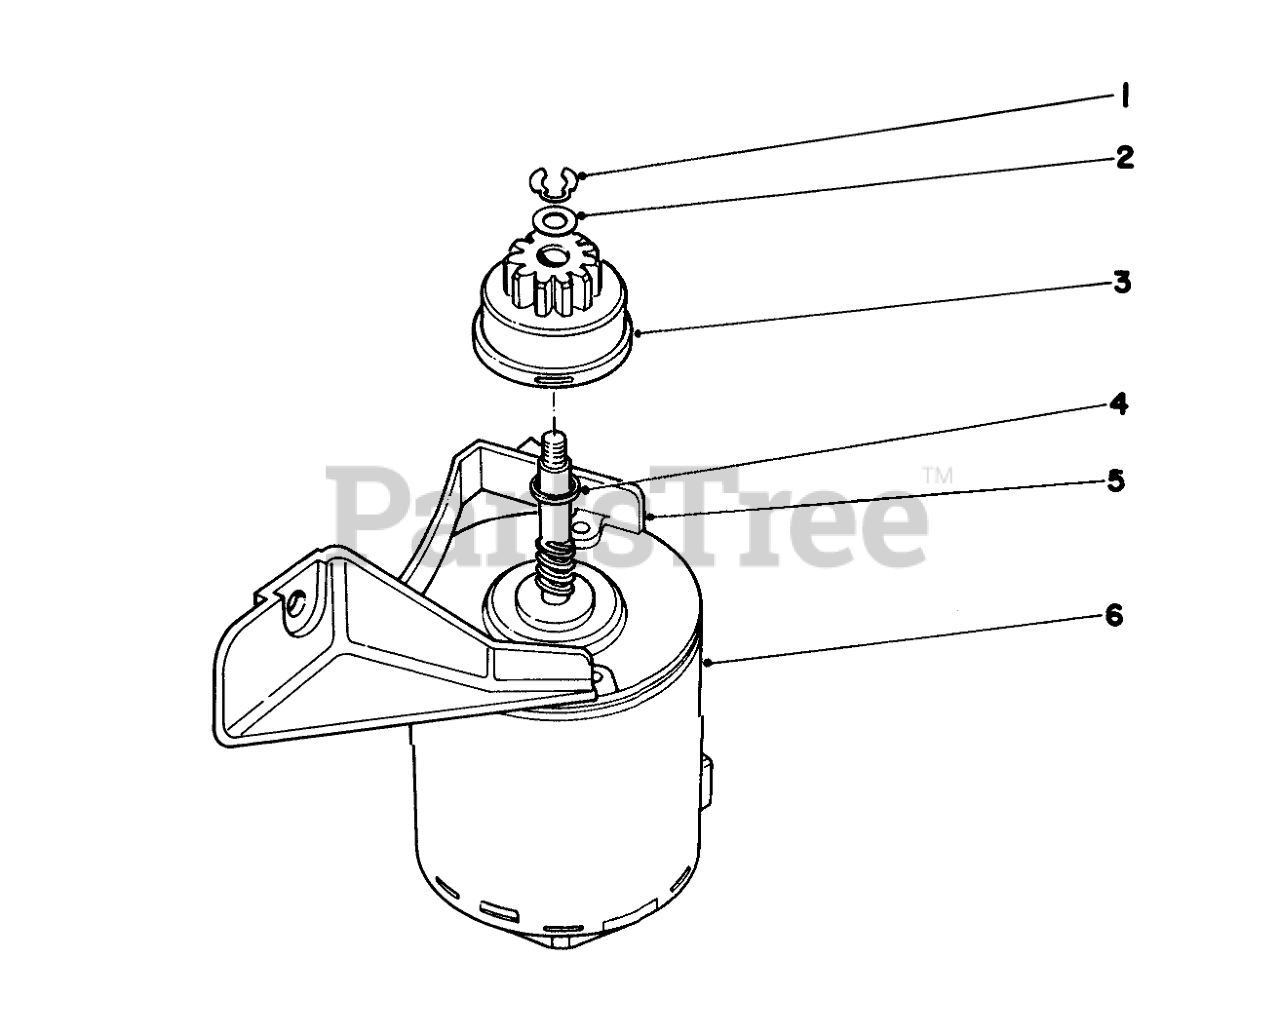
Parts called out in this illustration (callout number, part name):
1	RING-RETAINING
2	WASHER
3	PINION ASM
4	Spacer
5	Mounting Bracket
6	Starter Motor
